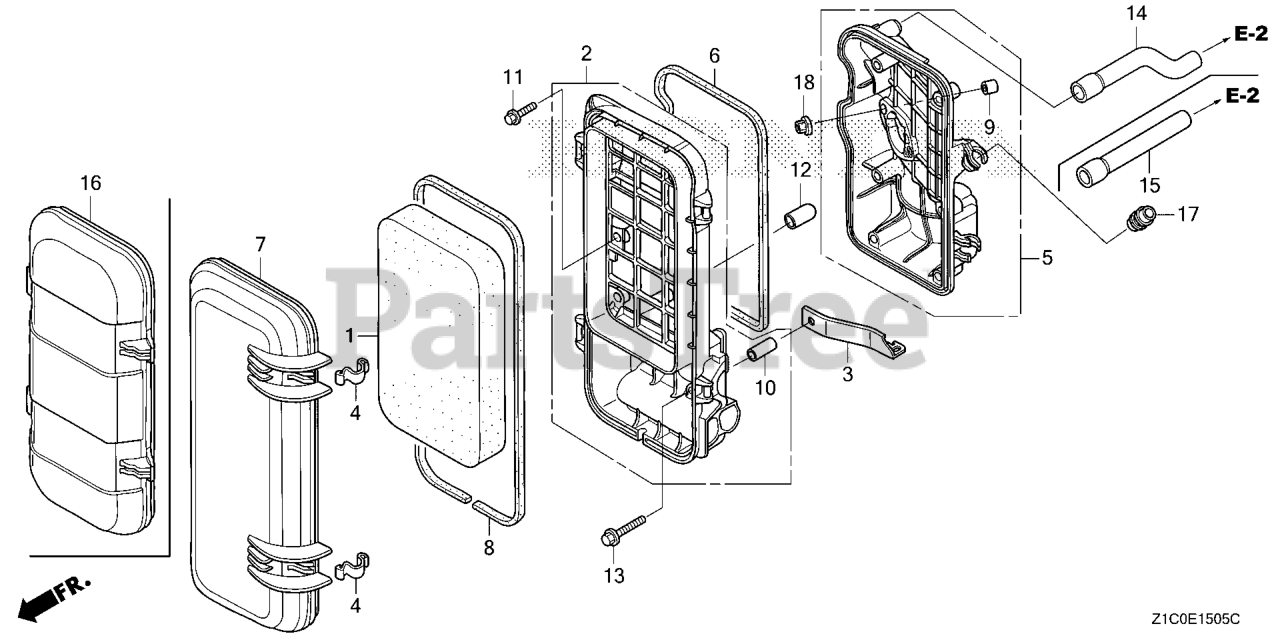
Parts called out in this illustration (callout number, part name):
1	ELEMENT, AIR CLEANER
2	HOUSING, AIR CLEANER
4	SPRING, AIR CLEANER HOUSING LID
5	BASE, AIR CLEANER
6	SEAL, AIR CLEANER HOUSING
7	COVER, AIR CLEANER
8	SEAL, AIR CLEANER COVER
9	COLLAR, AIR CLEANER
10	COLLAR, AIR CLEANER
11	BOLT, FLANGE (5X18)
12	CAP, SEALING
15	TUBE, BREATHER
17	RUBBER, FUEL (9X15X20)
18	NUT, FLANGE (6MM)
